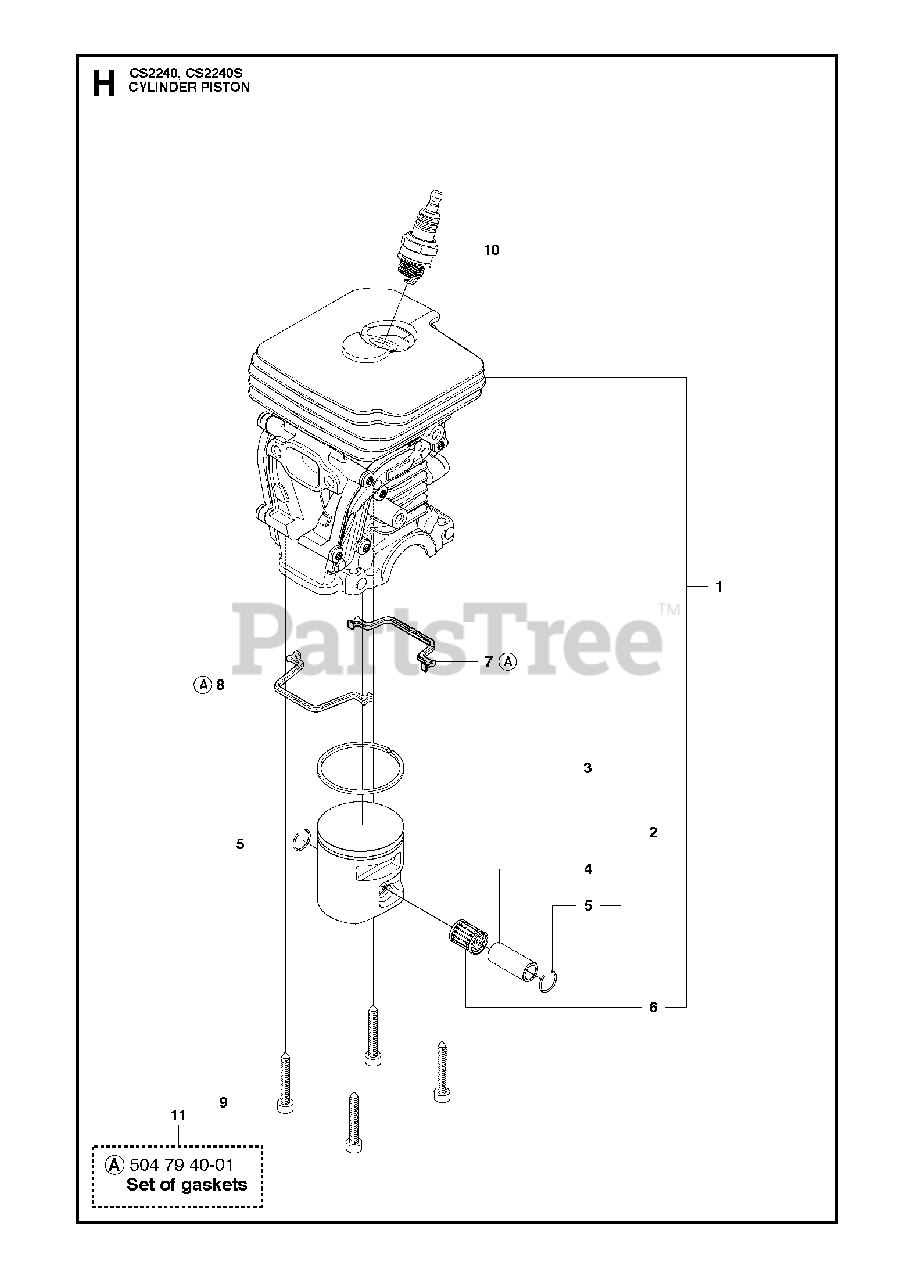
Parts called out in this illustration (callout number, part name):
1	ASSY, CYLINDER 435 & 435E
2	PISTON ASSY
3	PISTON RING
4	PISTON PIN
5	CIRCLIP
6	SUPPORT BUSHING
7	GASKET
8	GASKET
9	SCREW MC6S 5X25
10	BPMR7A NGK SPARK PLUG
11	GASKET SET
